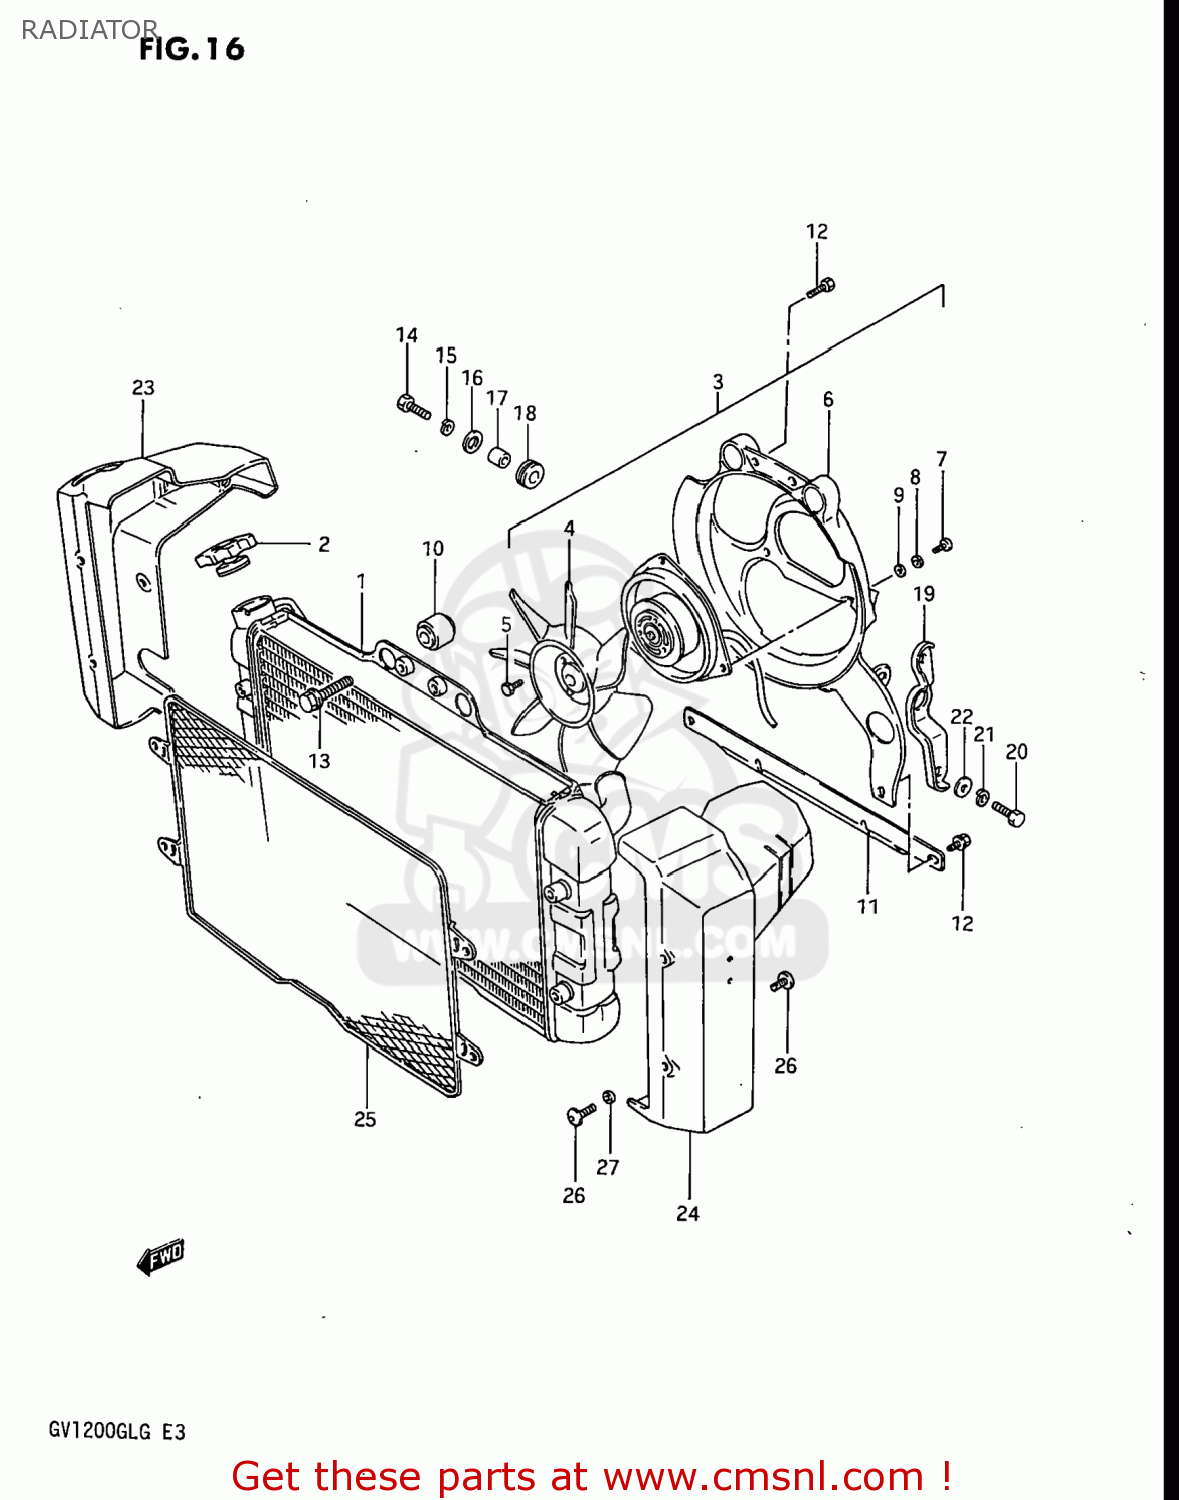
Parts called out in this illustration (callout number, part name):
1	RADIATOR ASSEMBLY,WATER
2	CAP,RADIATOR
3	FAN ASSEMBLY,RADIATOR (ASB)
4	FAN
5	BOLT
6	SHROUD,FAN
7	SCREW 5X10
8	LOCK WASHER
9	WASHER
10	CUSHION,RADIATOR NO.1
11	PLATE,MUD GUARD
12	BOLT,RADIATOR FAN
13	BOLT
14	BOLT 6X16
15	WASHER,LOCK
16	WASHER (6.5X18X1.6)
17	SPACER (7X9X7)
18	CUSHION
19	BRACKET,RADIATOR
20	BOLT 6X16
21	WASHER,LOCK
22	WASHER
23	COVER,RADIATOR,RIGHT
24	COVER,RADIATOR,LEFT
25	NET,RADIATOR
26	SCREW
27	SPACER (7X9X4)
